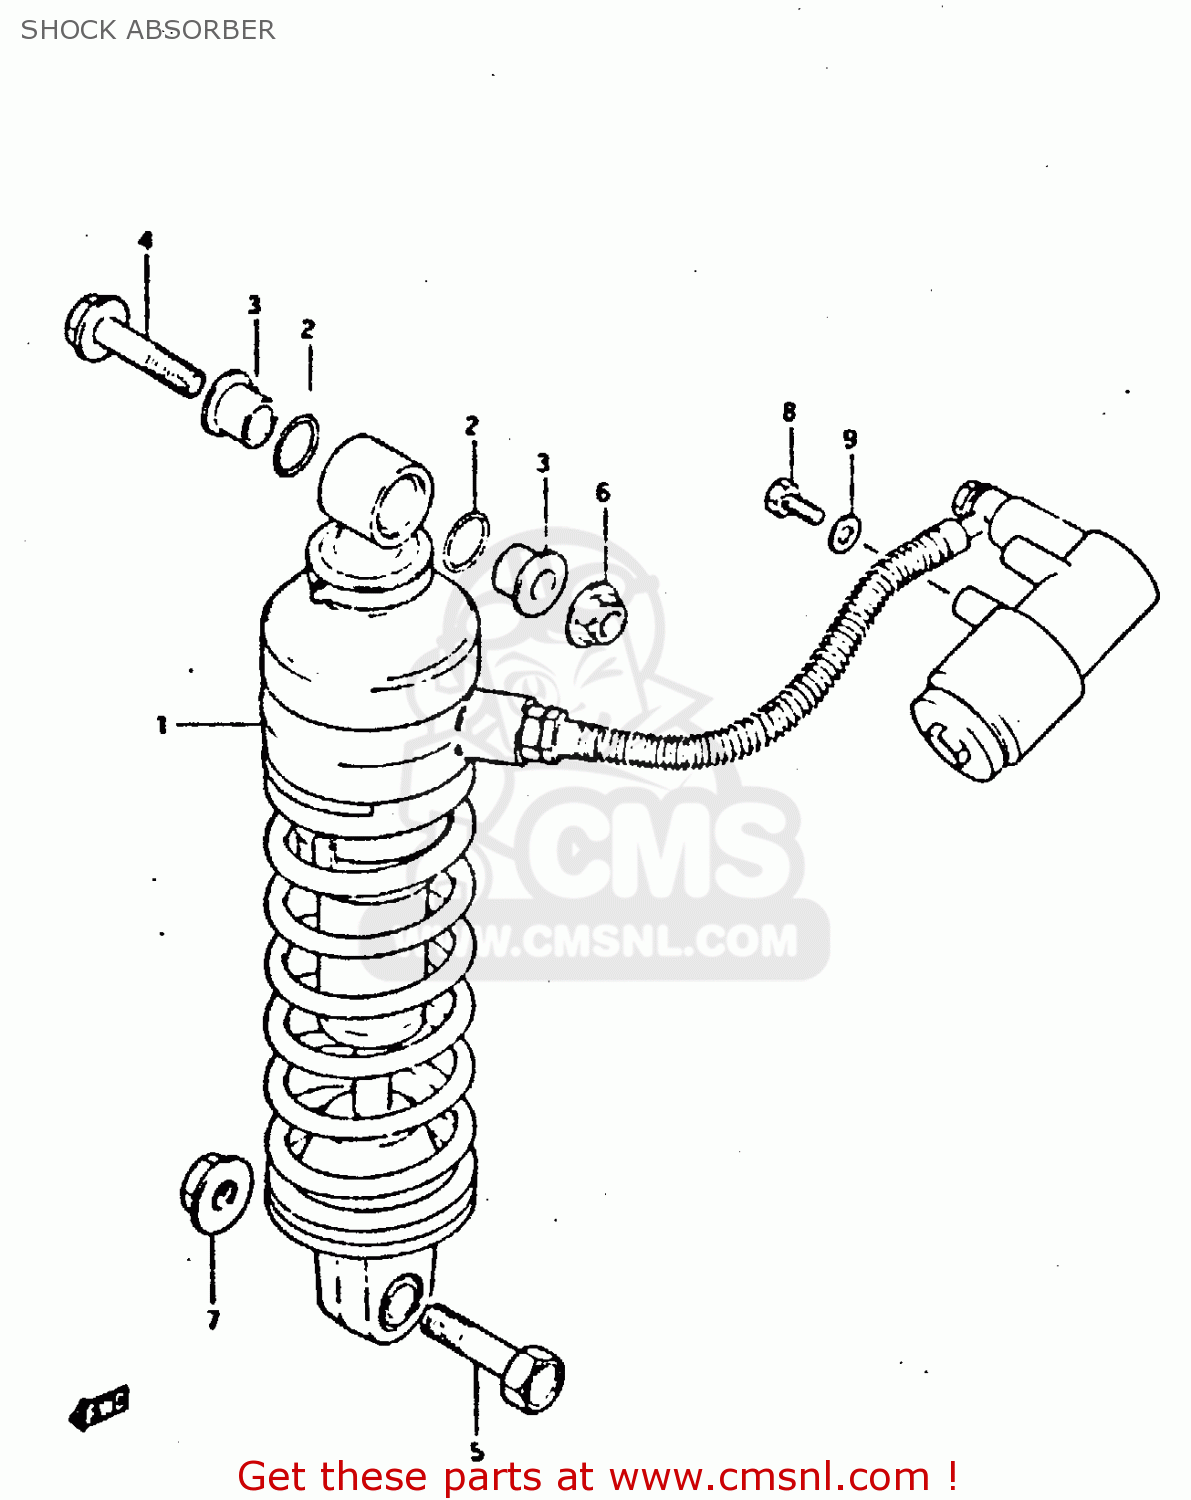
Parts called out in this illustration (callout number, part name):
1	ABSORBER ASSEMBLY,REAR SHOCK
2	DUST SEAL,LEVER CUSHION UNIT
3	SPACER,LEVER CUSHION UNIT
4	BOLT(10X50)
5	BOLT
6	NUT
7	NUT 12MM
8	SCREW(6X12)
9	WASHER
